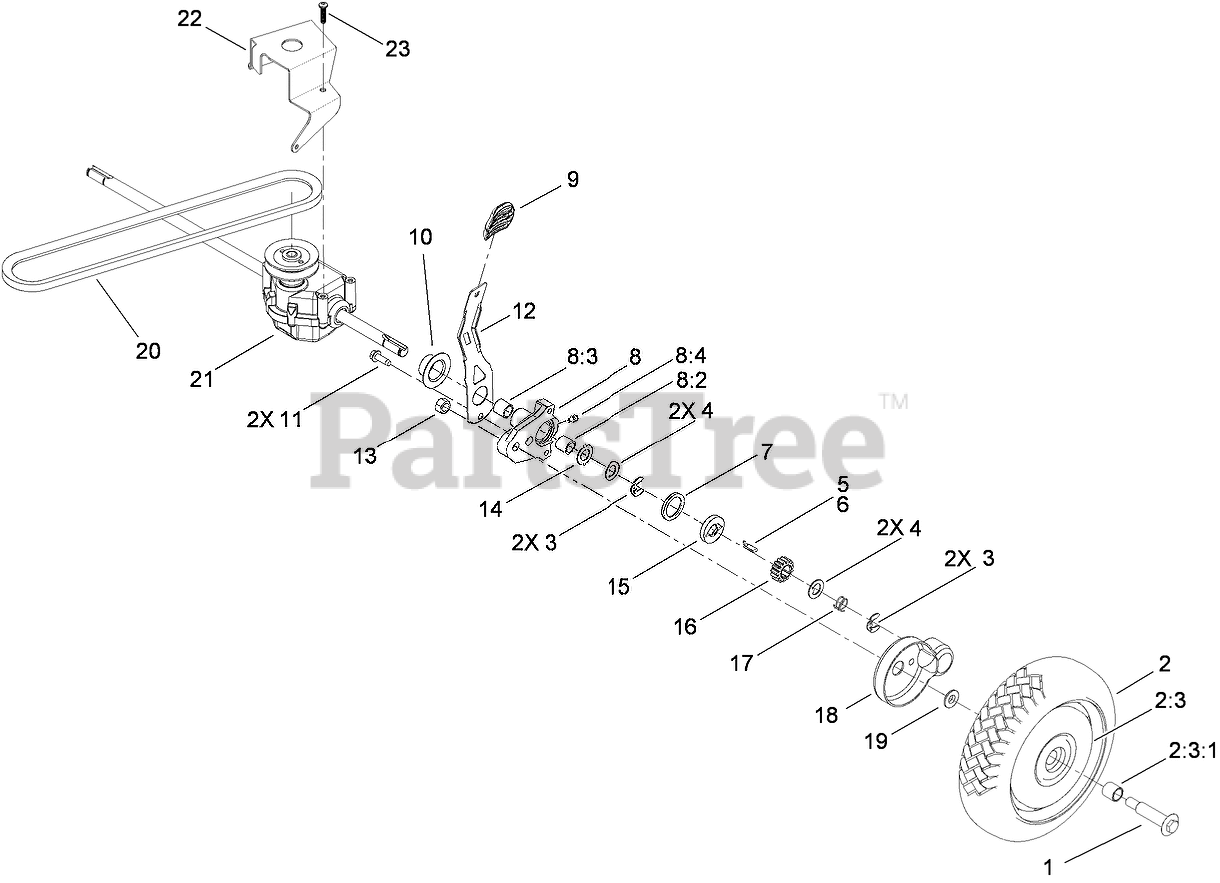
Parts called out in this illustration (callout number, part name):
1	BOLT-SHOULDER
2	WHEEL AND TIRE ASM (W/GEAR)
2:3	WHEEL ASM
2:3:1	BUSHING
3	RING-CLIP, LOCKING
4	WASHER-THRUST, KEYED
5	KEY-ROCKING, RH
6	KEY-ROCKING, LH
7	RING-FRICTION
8	PIVOT ARM ASM
8:2	BUSHING
8:3	BUSHING
8:4	FITTING-GREASE
9	Knob-Lever, HOC
10	CAP-END
11	SCREW-HWHTF
12	ARM-SPRING
14	WASHER-ARM, PIVOT
15	WASHER-CLUTCH
16	GEAR-PINION
17	SPRING-COMPRESSION
18	COVER-WHEEL
19	SPACER-COVER, WHEEL
20	V-BELT
21	TRANSMISSION ASM
22	BRACKET-TRANSMISSION
23	SCREW-PLASTITE
